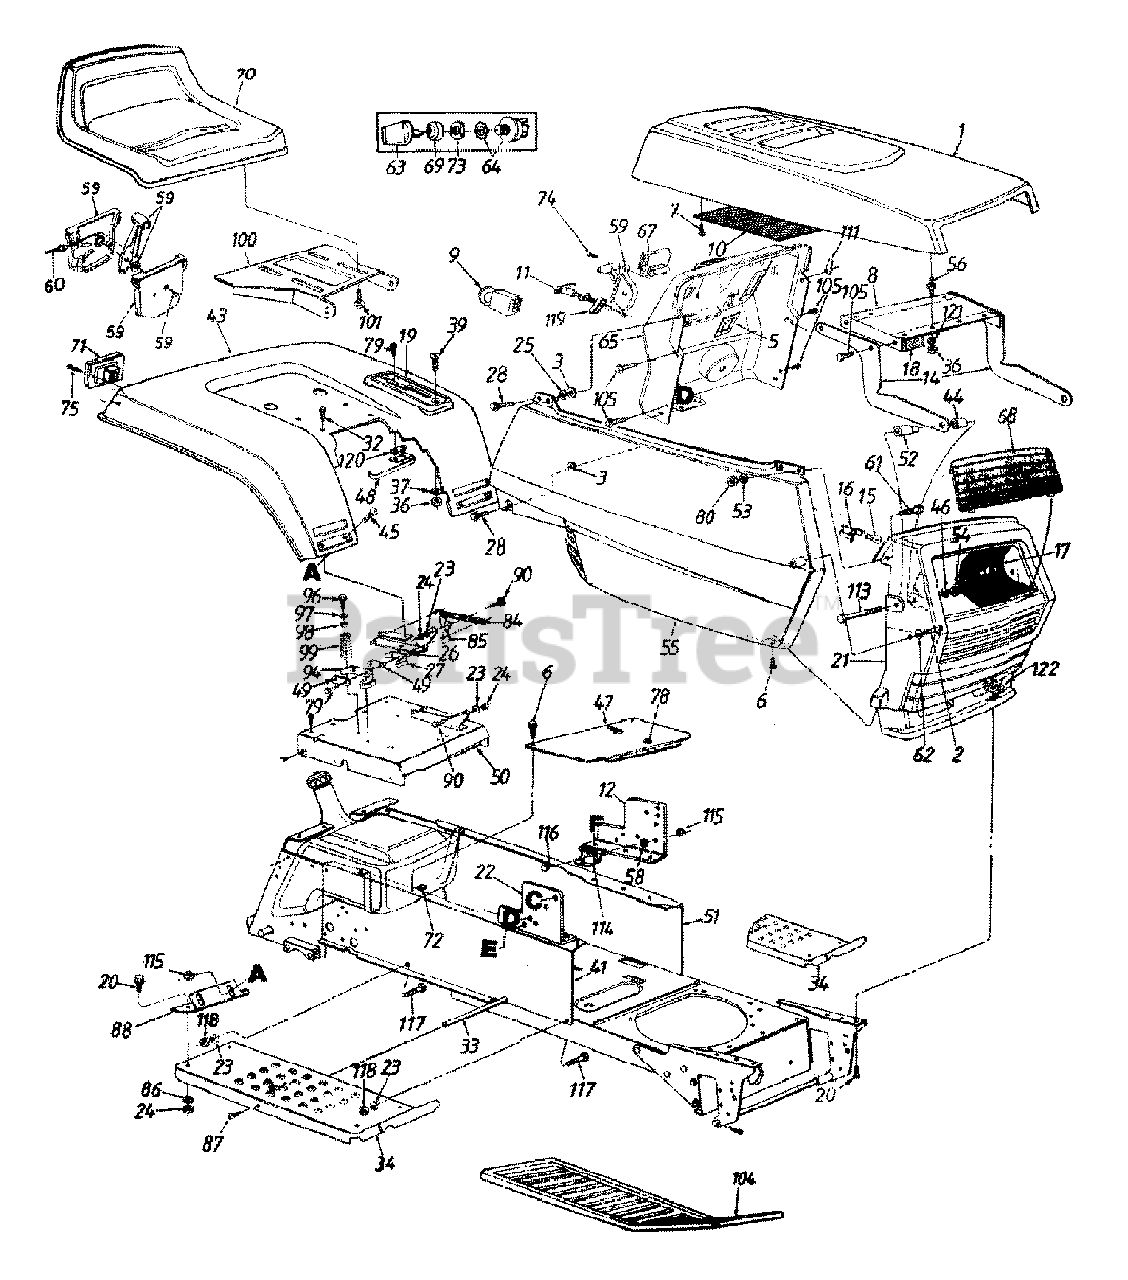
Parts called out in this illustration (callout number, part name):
1	Hood
2	Hex Wash. B-Tap Scr. 1/4 x .62" Lg.
3	Bolt Retainer 1/4" I.D.
5	Switch Retainer
6	Truss Mach. B-Tap Scr. #10 x .5" Lg.
7	Hex Wash. Hd. AB-Tap Scr #8 x .5" Lg.
11	Choke Control
16	Twist Lock - Lamp Socket
17	Reflector - Headlight
19	Speed Control Index Brkt.
20	Hex Bolt 5/16-18 x .75" Lg.
21	Grille
24	Hex Sems Nut 5/16-18 Thd.
25	Fl-Wash. 1/4" I.D. x .93" O.D.
26	Insulator Boss Plate
27	Seat Spring Switch
28	Hex Wash. TT-Tap Scr. 1/4-20 x .75" Lg.
32	Hex Wash. Hd. AB-Tap Scr. 5/16 x .75" Lg.
33	Running Board Rod
37	L-Wash. 1/4" I.D.
39	Truss Mach. Scr. 1/4-20 x 1.0" Lg.
45	Carriage Bolt 1/4-20 x .50" Lg.
46	Fl-Wash. .328" I.D. x .68" O.D.
49	Insulator Plate
50	Seat Plate
53	Fl-Wash. .281" I.D. x .5" O.D.
54	Hex Cent. L-Nut 5/16-18 Thd.
55	Side Cover Ass'y. - R.H.
56	Double Ended Stud 1/4-20 Thd.
58	Ext. L-Wash. 1/4" I.D.
59	Throttle Control Box Ass'y.
60	Throttle Control Wire 39" Lg.
61	Hex Bolt 1/4-20 x .62" Lg.
62	Fl-Wash. .281" I.D. x .73" O.D.
64	Ignition Switch
65	Dash Panel
67	Ammeter
68	Lens
69	Ignition Switch Cap
70	Seat Ass'y.
71	Taillight Ass'y.
72	Speed Nut #10Z
73	Ignition Switch Nut
74	Truss Mach. AB-Tap Scr. #10 x .5" Lg.
75	Truss Hd. AB-Tap Scr. #6 x .62"
78	Snap Bushing
79	Hex Wash. Hd. AB-Tap Scr. #8 x .50" Lg.
80	Hex L-Nut 1/4-20 Thd.
84	Ext. Spring 5.31" Lg.
85	Seat Lift Brkt.
86	Bell-Wash. .345" I.D. x .88" O.D.
87	Truss Machine Scr. 5/16-18 x .75" Lg.
94	Spring Switch
96	Hex Flange TT-Scr. 5/16-18 x .875"
97	Fl-Wash. 5/16" I.D.
99	Compression Spring
101	Hex Tap Scr. 3/8-16 x .62" Lg.
105	Hex Tap Scr. 1/4-20 x .5" Lg.
111	Speed Nut 1/4-20 Thd.
113	Hex Bolt 5/16-18 x 2.75"
114	Solenoid
115	Hex Sems Nut 1/4-20 Thd.
116	Hex Bolt 1/4-20 x .5" Lg.
117	Rib Neck Bolt 5/16-24 x .75" Lg.
118	Hex Nut 5/16-24 Thd.
119	Retainer Clip
120	Insulator Nut Plate
121	Bell-Wash. .265" I.D. x .75" O.D.
122	U-Nut 5/16-18 Thd.
17393B-0499	COVER-TRANSMISSION - CUB BEIGE (0499)
17393B-0637	COVER-TRANSMISSION - POWDER BLACK (0637)
17393B-0638	COVER-TRANSMISSION - MTD/TROY-BILT RED (0638)
17393B-0648	COVER-TRANSMISSION - TECH GRAY (0648)
17393B-0665	COVER-TRANSMISSION - YARDMAN GREEN (0665)
